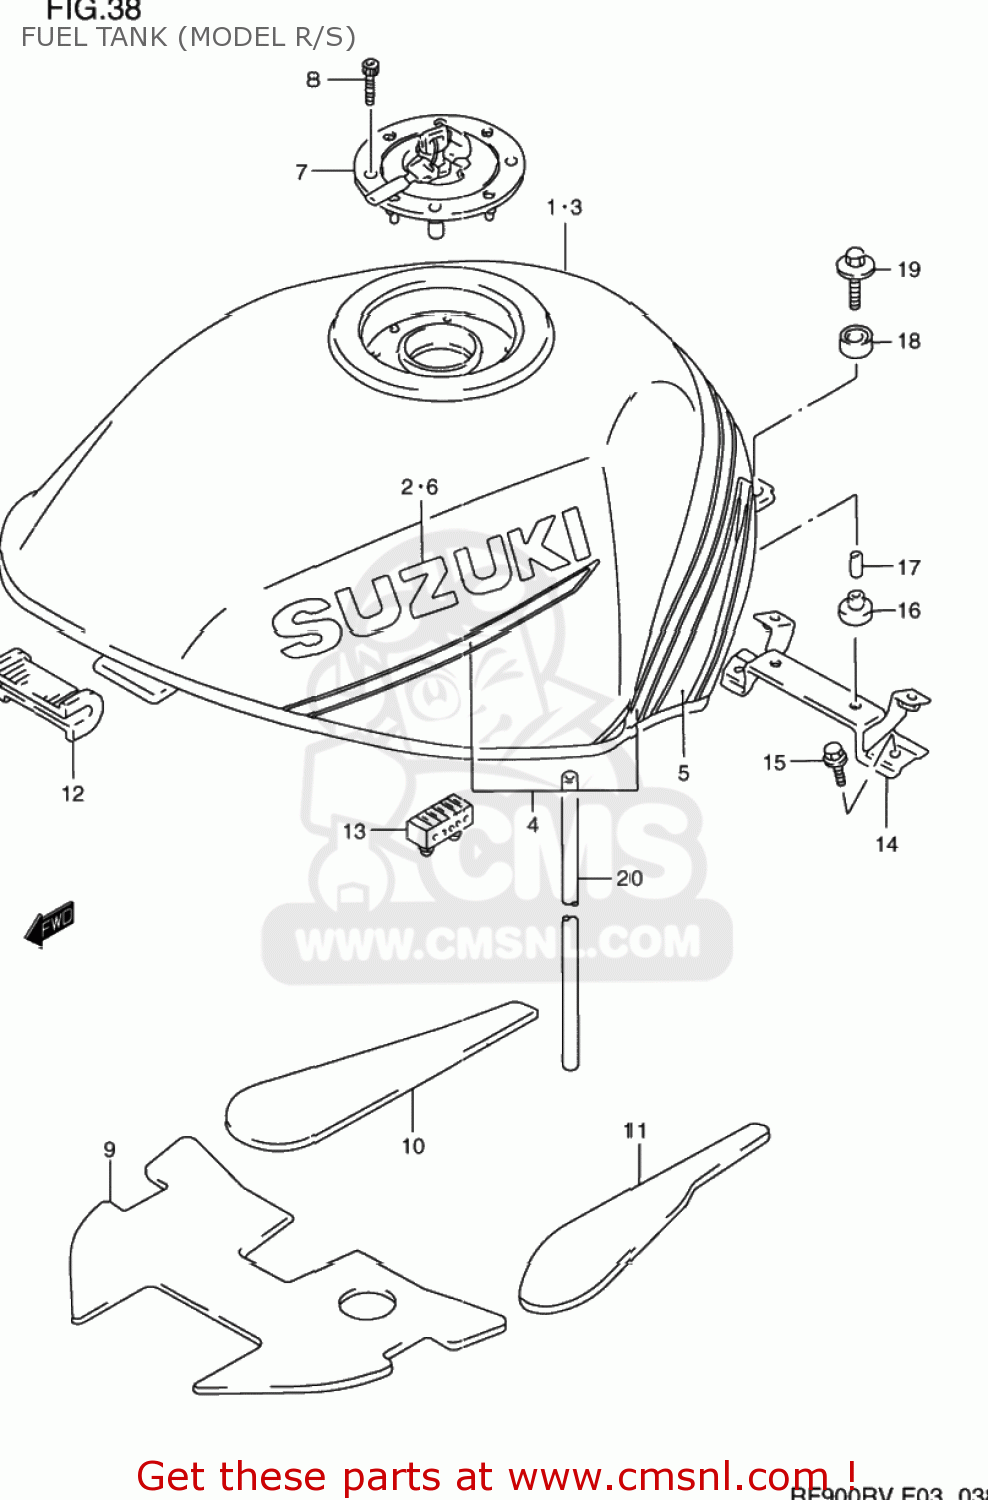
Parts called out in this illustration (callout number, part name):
1	TANK ASSEMBLY,FUEL
2	EMBLEM,FUEL TANK
3	TANK ASSY,FUEL
4	TAPE SET,FUEL TANK
5	TAPE SET,FUEL TANK
6	EMBLEM,FUEL TANK
7	CAP SET,FUEL
8	BOLT(5X20)
9	SHIELD,FUEL TANK HEAT NO.1
10	SHIELD,FUEL TANK HEAT NO.2
11	SHIELD,FUEL TANK HEAT NO.3
12	CUSHION,FUEL TANK FR
13	CUSHION,SEAT(40X20X15)
14	BRACKET,FUEL TANK RR
15	BOLT
16	CUSHION
17	SPACER
18	CUSHION
19	BOLT
20	HOSE(7X10.2X600)
